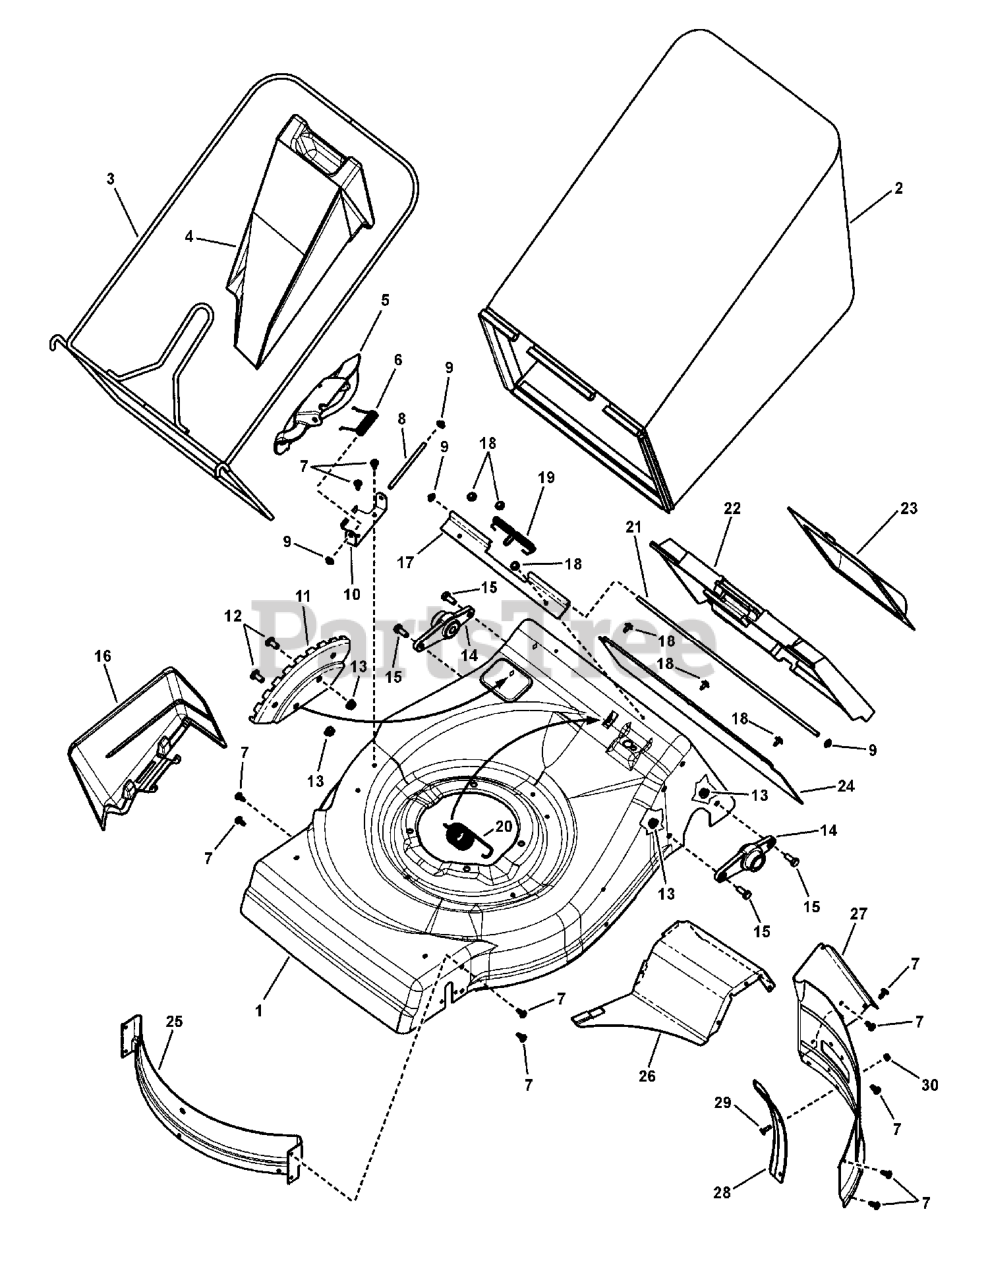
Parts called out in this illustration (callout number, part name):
1	DECK, 21" Rear Discharge, Non-Electric Start
2	GRASSBAG, 21" Rear Discharge
3	BAG FRAME, 21" RD WBM
4	PLUG, Mulching
5	COVER, 21" Mulching
6	SPRING, Torsion, Chute
7	SCREW, 1/4-20 x .550 Pan Head Self-Tap (Torx)
8	ROD, Mulch Cover Pivot
9	PUSHNUT, 1/4"
10	BRACKET, Chute Deflector
11	INDEX PLATE, Height-Of-Cut, 21" WBM, RD
12	BOLT, 5/16-18 x 3/4" Round Head Short Square Neck, GR 5, YZ
13	NUT, 5/16-18 Hex Flange lock, YZ
14	ASSEMBLY, Bearing Holder, 21" WBM, Rear Discharge
15	SCREW, 5/16-18 x 3/4" Hex Head Cap, GR 5, YZ
16	CHUTE, 21" Side Discharge
17	SPACER, Rear Door, 21" WBM
18	SCREW, #10-24 x .50 Hex Washer Self-Tap Sems
19	SPRING, Torsion
20	SPRING, Extension, Height-Of-Cut Assist
21	ROD, Rear Door Pivot, 21" Rear Discharge
22	DOOR, 21" Black
23	TRANSMISSION COVER, Rear, 21" WBM
24	DEFLECTOR, Rear, 21" WBM, RD
25	BAFFLE, Front 21" WBM, RD
26	BAFFLE, Right Rear, 21" Walk-Behind-Mower, RD
27	BAFFLE, Left Rear, 21" Rear Discharge, WBM
28	BAFFLE, Extension, 21" RD WBM
29	BOLT, #10-24 x 5/8" Flat Head Square Neck, YZ
30	NUT, #10-24 Hex Nyloc
